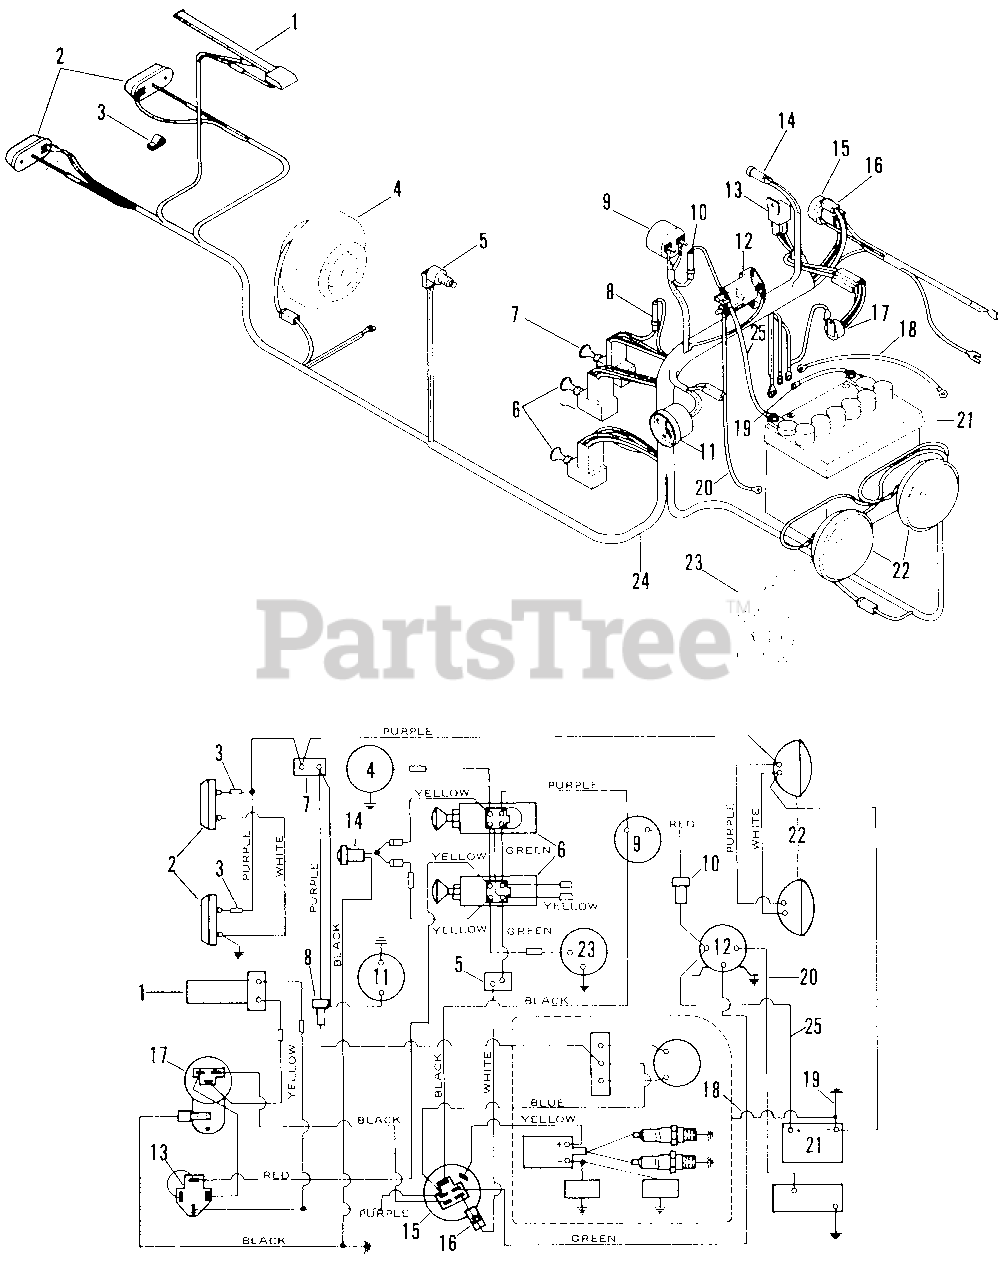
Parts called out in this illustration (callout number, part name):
1	Switch Seat
2	Tail Light Assembly
3	Wire Clip
4	Electric Clutch
5	Safety Switch
6	Clutch Switch
7	Light Switch
8	SAE 7 Amp Fuse
9	Ammeter
10	SAE 30 Amp Fuse
11	Hourmeter
12	Solenoid
13	Relay
14	PTO Indicator Light
15	Switch and Key Set Assembly
16	Diode Assembly
17	Time Delay Module
18	Cable
19	Cable, Ground
20	Cable, Starter
21	Battery
22	Headlight
23	Clutch Assembly 1.12 Bore
24	Wiring Harness
25	Cable, Starter
